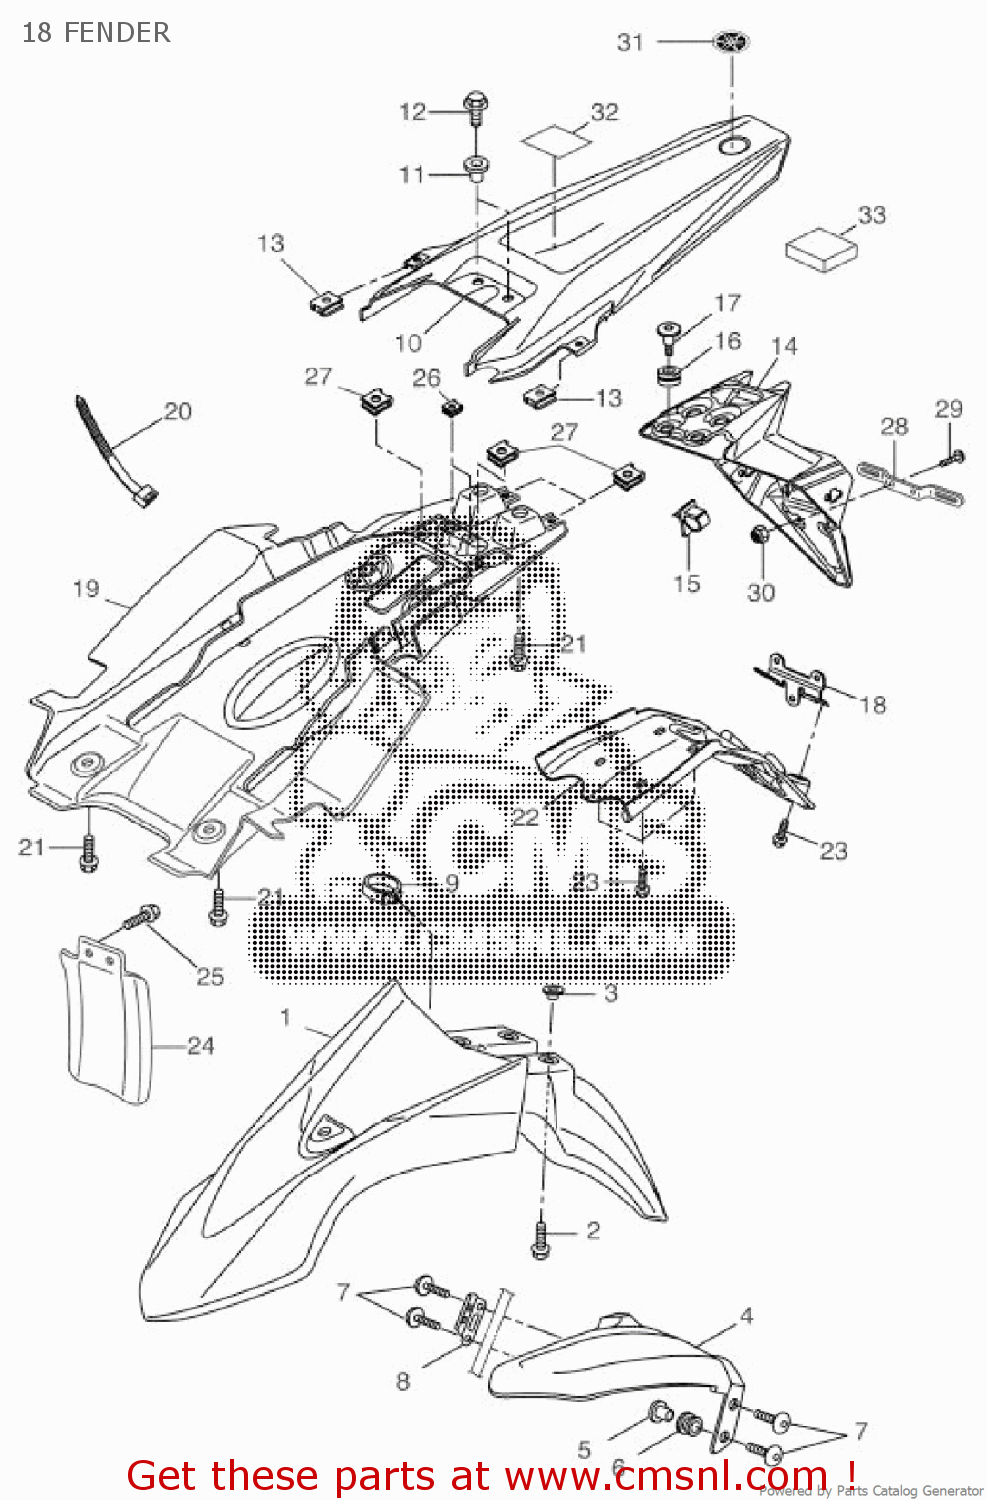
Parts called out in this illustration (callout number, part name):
1	FENDER FRONT
2	BOLT, WITH WASHER (36X)
3	COLLAR(50M)
4	FENDER FRONT 2
5	COLLAR (22F)
6	GROMMET(53Y)
7	BOLT, HEXAGON SOCKET HEAD(3GM)
8	BRACKET
9	CLAMP
10	FENDER REAR
11	COLLAR
12	BOLT HEX SOCKET BUTTON
13	NUT, SPRING
14	BRACKET LICENSE
15	CLAMP
16	GROMMET
17	BOLT HEX
18	BRACKET REAR STAY
19	CAP
20	BAND,SWITCH CORD
21	BOLT
22	CAP
23	BOLT
24	GUARD FLAP
25	BOLT
26	NUT, SPRING(47R)
27	NUT, SPRING
28	BRKT LICENSE
29	BOLT, WASHER BASED
30	NUT, SELF-LOCKING(2TK)
31	EMBLEM
32	LABEL WARNING
33	DAMPER
